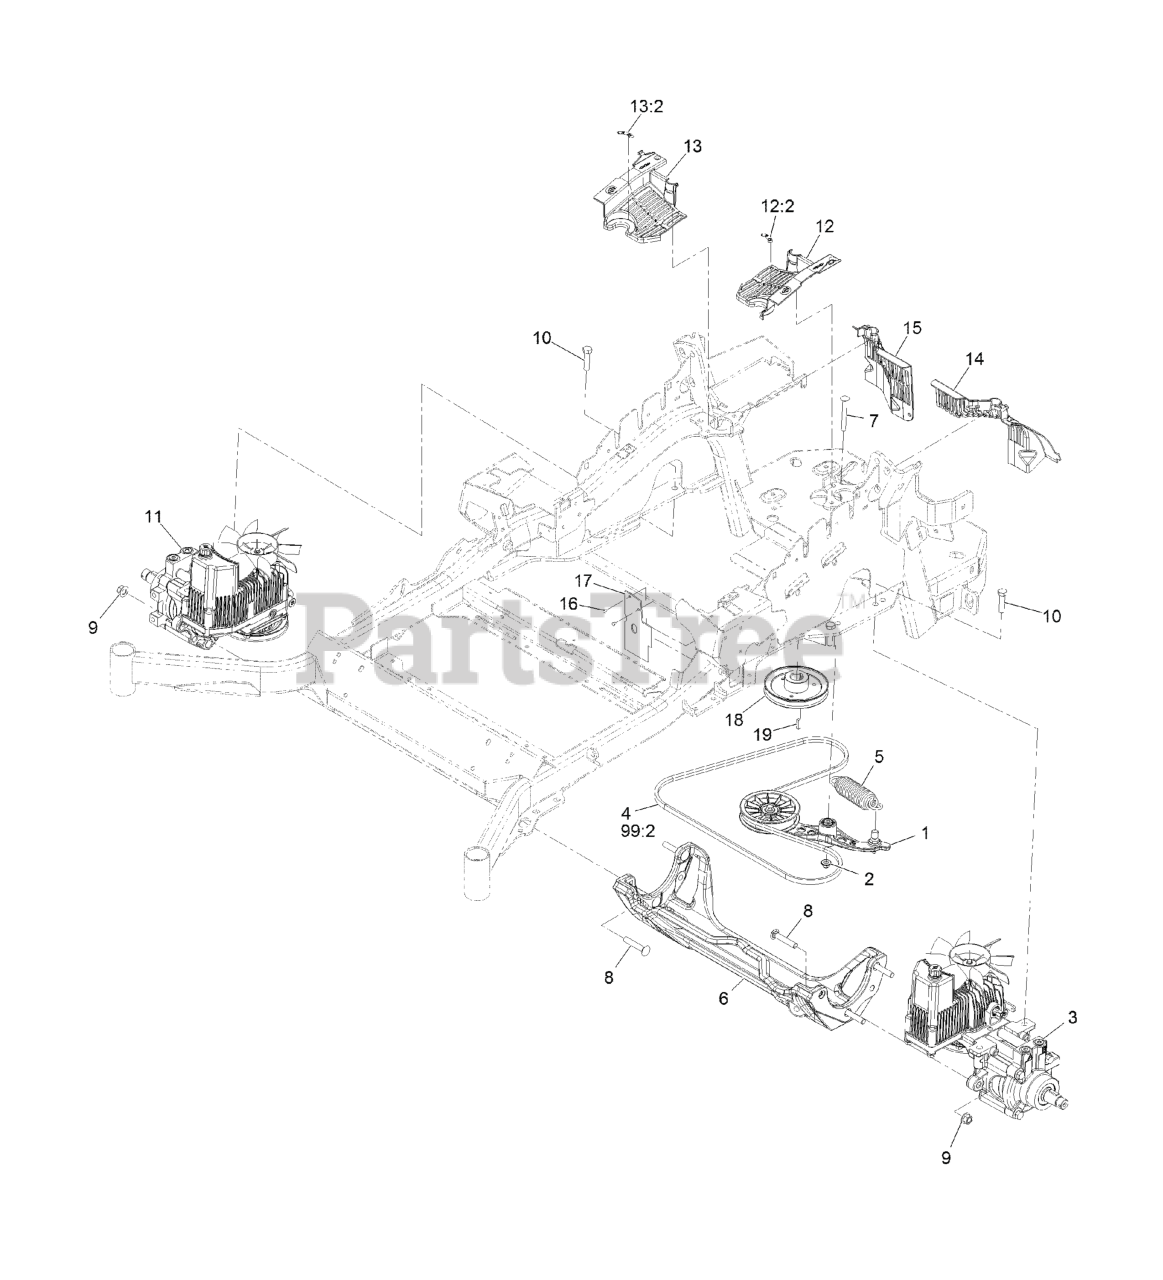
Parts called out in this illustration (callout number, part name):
1	PUMP IDLER ASM
2	Nut-Nyloc 3/8-16 Flg
3	LH Hydro ASM (16Cc W/ Shock)
4	BELT
5	SPRING-EXTENSION
6	CRADLE-HYDRO
7	BOLT-SHOULDER, CARRIAGE 3/8-16 X 3 1/2
8	SCREW-CARR
9	Nut-Lock 1/2-13
10	SCREW-HH
11	RH Hydro ASM (16Cc W/ Shock)
12	LH HYDRO GUARD ASM
12:2	DECAL-OIL, HYDRO
13	RH HYDRO GUARD ASM
13:2	DECAL-OIL, HYDRO
14	GUARD-HYDRO REAR, LH TRIM
15	GUARD-HYDRO, REAR (RH)
16	RIVET-POP
17	DEFLECTOR-AIR FLOW
18	SHEAVE
99:2	BELT
